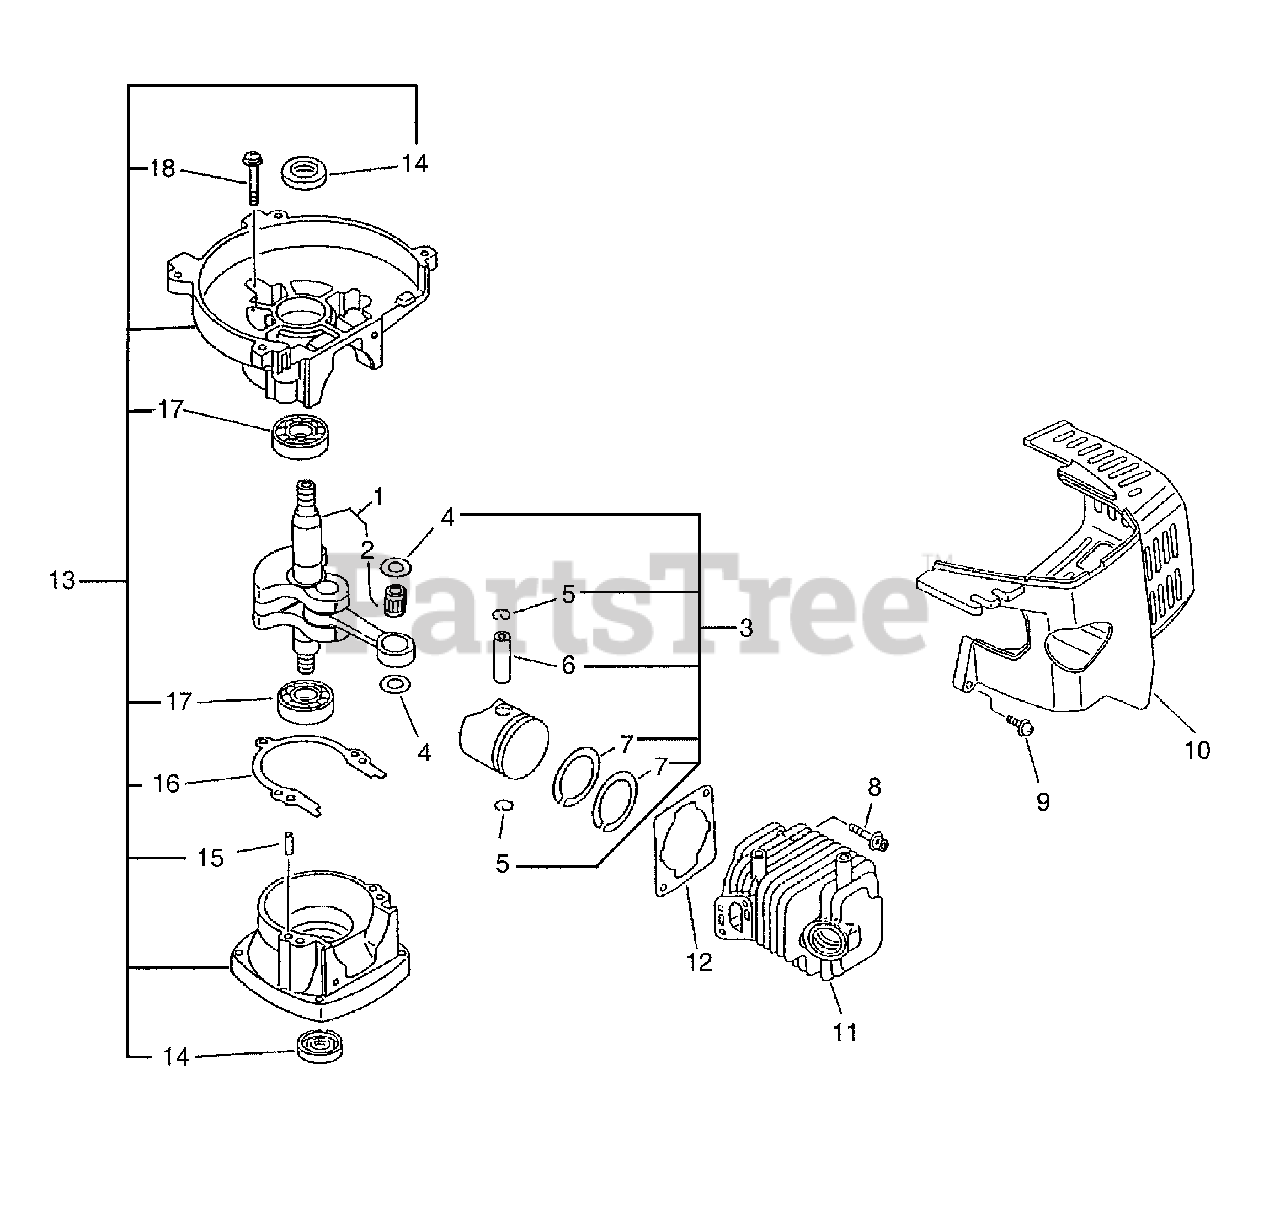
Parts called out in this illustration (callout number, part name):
1	CRANKSHAFT ASSY
2	BEARING, NEEDLE - 8
3	PISTON KIT
5	RING, RETAINING
6	PIN, PISTON
7	RING, PISTON
8	SCREW - 5X22
9	SCREW - 4X22
10	COVER, ENGINE
11	CYLINDER
12	GASKET, CYLINDER
13	CRANKCASE KIT
14	SEAL, OIL
15	PIN - LOCATING
16	GASKET, CRANKCASE
17	BEARING, BALL - 6201
18	SCREW - 5X28
